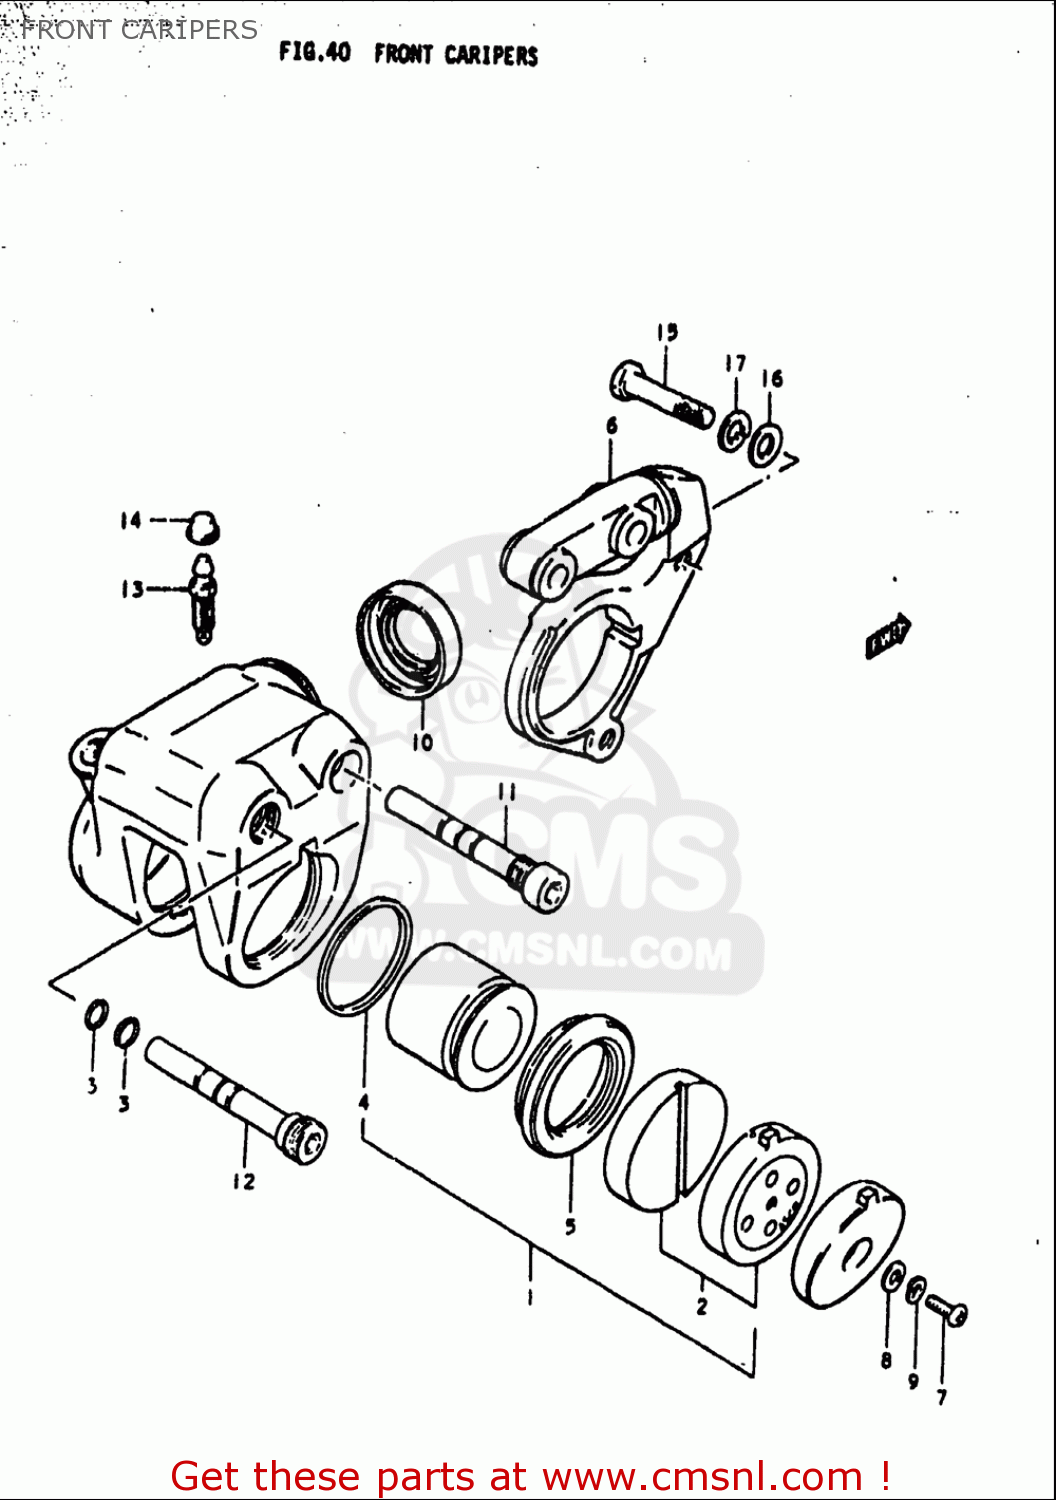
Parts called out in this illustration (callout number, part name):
2	PAD SET (NAS)
3	O RING,AXLE CALIPER
4	SEAL,PISTON
5	BOOT,PISTON
6	HOLDER,CALIPER
7	SCREW
8	WASHER
9	WASHER,LOCK
10	BOOT,HOLDER
11	AXLE,CALIPER
12	AXLE NO.2
13	BLEEDER
14	CAP,BLEEDER PLUG
15	BOLT(10X38)
16	WASHER(10.5X20X2.3)
17	WASHER,LOCK
